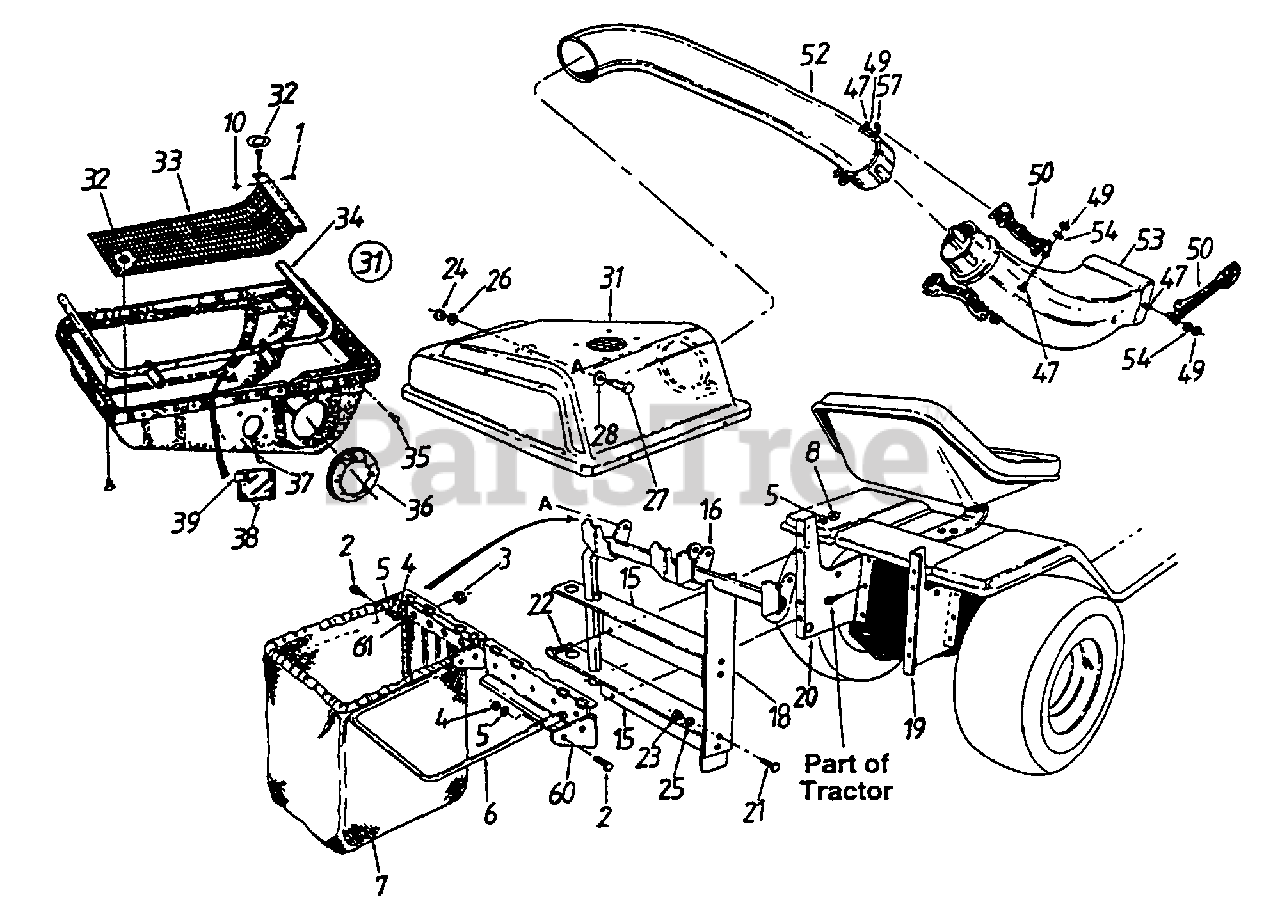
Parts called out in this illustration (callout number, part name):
1	Pop Rivet .188 Dia.
2	Hex Bolt 1/4-28 x .88"
3	Hex Sems Nut #10-24 Thd.
4	Hex Nut 1/4-28 Thd.
5	L-Wash. 1/4" I.D.
7	Grass Catcher Bag
8	Hex Nut 1/4-20 Thd.
10	Flat Wash. 1/4" I.D.
22	Hex Bolt 1/4-20 x.62" Lg.- Grade 5
23	Hex Nut 5/16-18 Thd.
24	Hex Nut 3/8-16 Thd.
25	L-Wash. 5/16" I.D.
26	L-Wash. 3/8" I.D.
27	Shld. Bolt 3/8-16 x .50" Dia.
28	Bell-Wash .505" I.D. x 1.0" O.D.
31	Grass Catcher Cover Ass'y.
32	Twist Fastener
35	Hex AB-Tap Scr. 1/4 x .62"
36	Seal - 7"
37	Truss B-Tap Scr. #10 x .5" Lg.
38	Plastic Plate
39	Speed Nut
47	Hex Bolt 1/4-20 x .625"
49	Hex Ins. L-Nut 1/4-20 Thd.
50	Retainer Strap Ass'y.
52	Catcher Tube
53	Discharge Chute
54	L-Wash .27" I.D.
57	Retainer Hook Brkt.
61	Truss Mach. Scr. #10-24 x .5"
